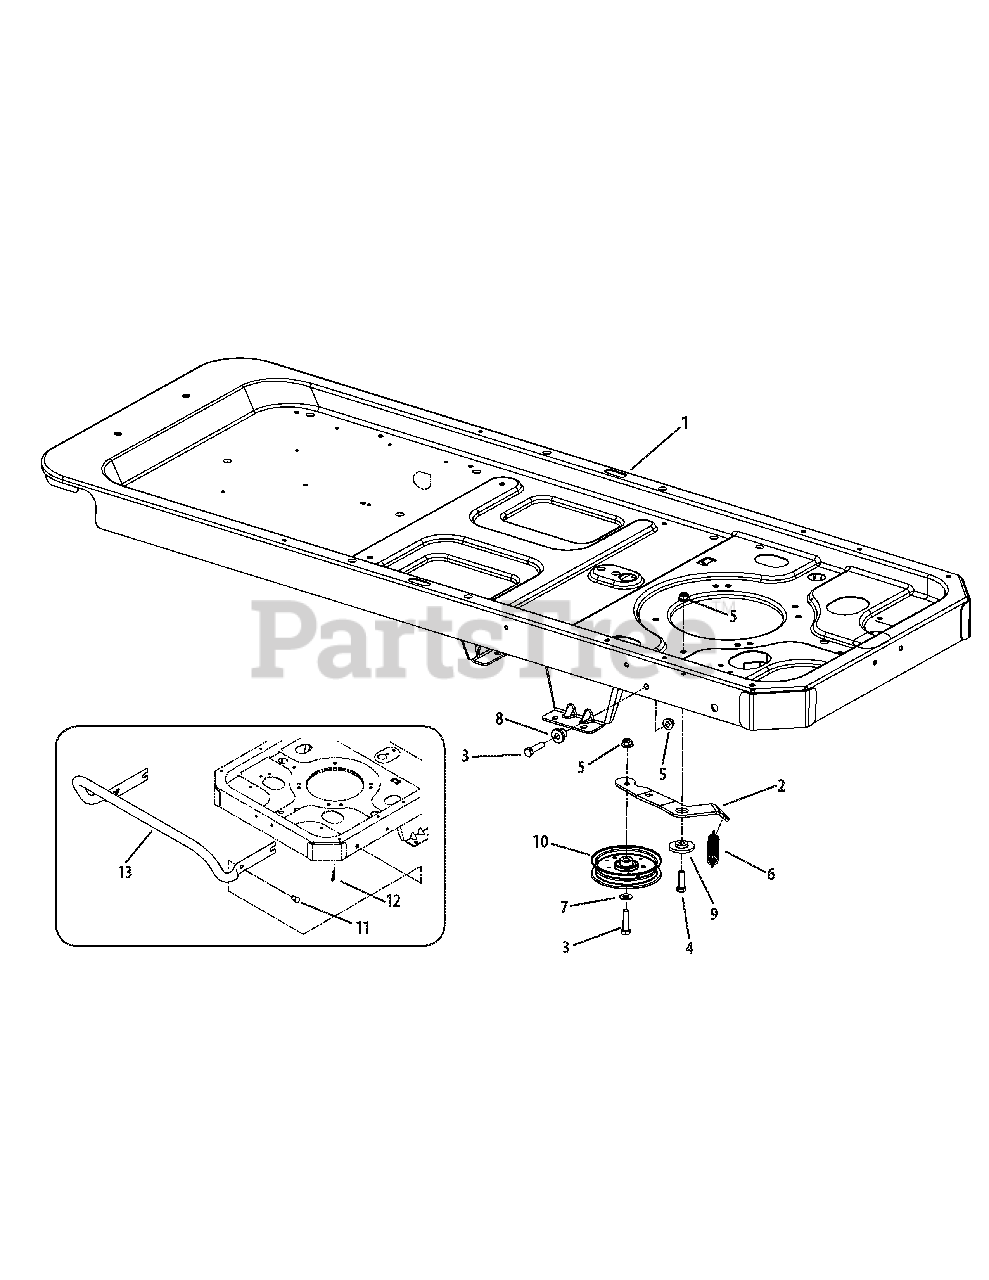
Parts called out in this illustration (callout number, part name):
1	Frame
2	Idler Arm
3	Hex Cap Screw, 3/8-16 x 1.5
4	Hex Cap Screw, 3/8-16 x 1.25
5	Hex Flange Lock Nut, 3/8-16
6	Extension Spring, .75 x 5.06
7	Flat Washer, .406 x .875 x.059
8	Shoulder Spacer, .38 x 1.0 x .7
9	Shoulder Spacer, .884 x 1.9
10	Idler Pulley
11	Clevis Pin, .50 x .78
12	Cotter Pin, .080 x 1.5625
13	Bumper
